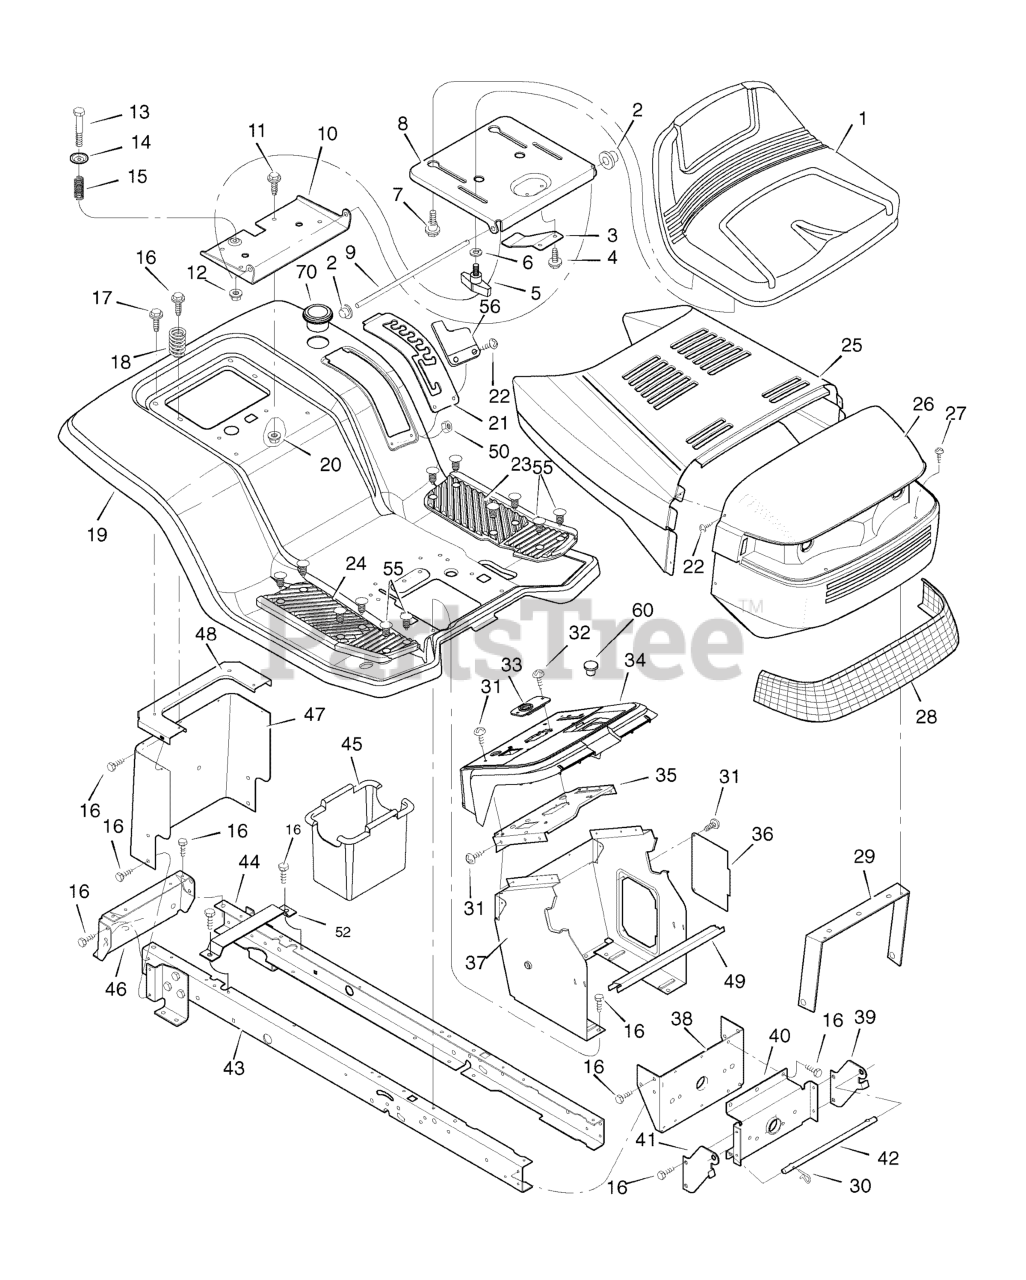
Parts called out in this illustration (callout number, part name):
2	Cap, Push 0n
5	Bolt, Wing
6	Washer
7	Bolt, Shoulder
8	Support, Seat
9	Rod, Pivot
10	Bracket, Pivot
11	Bolt
13	Bolt, Shoulder
20	Nut
21	Plate, Index
23	Mat, Left
24	Mat, Right
29	Brace, Grille
30	Pin, Hair
33	Bearing, Steering
35	Plate, Dash
36	Panel, Access
37	Support, Dash
38	Support, Rear Hanger
39	Support, Left Grille
40	Axle, Hanger
41	Support, Right Grille
42	Rod, Pivot
43	Frame, Right
44	Frame, Left
45	Container, Battery
46	Plate, Hitch
47	Plate, Rear
48	Top, Rear Plate
52	Bracket, Battery Support
55	Fastener, Panel
56	Cover, Detent
60	Plug, Dash
70	Holder, Cup
